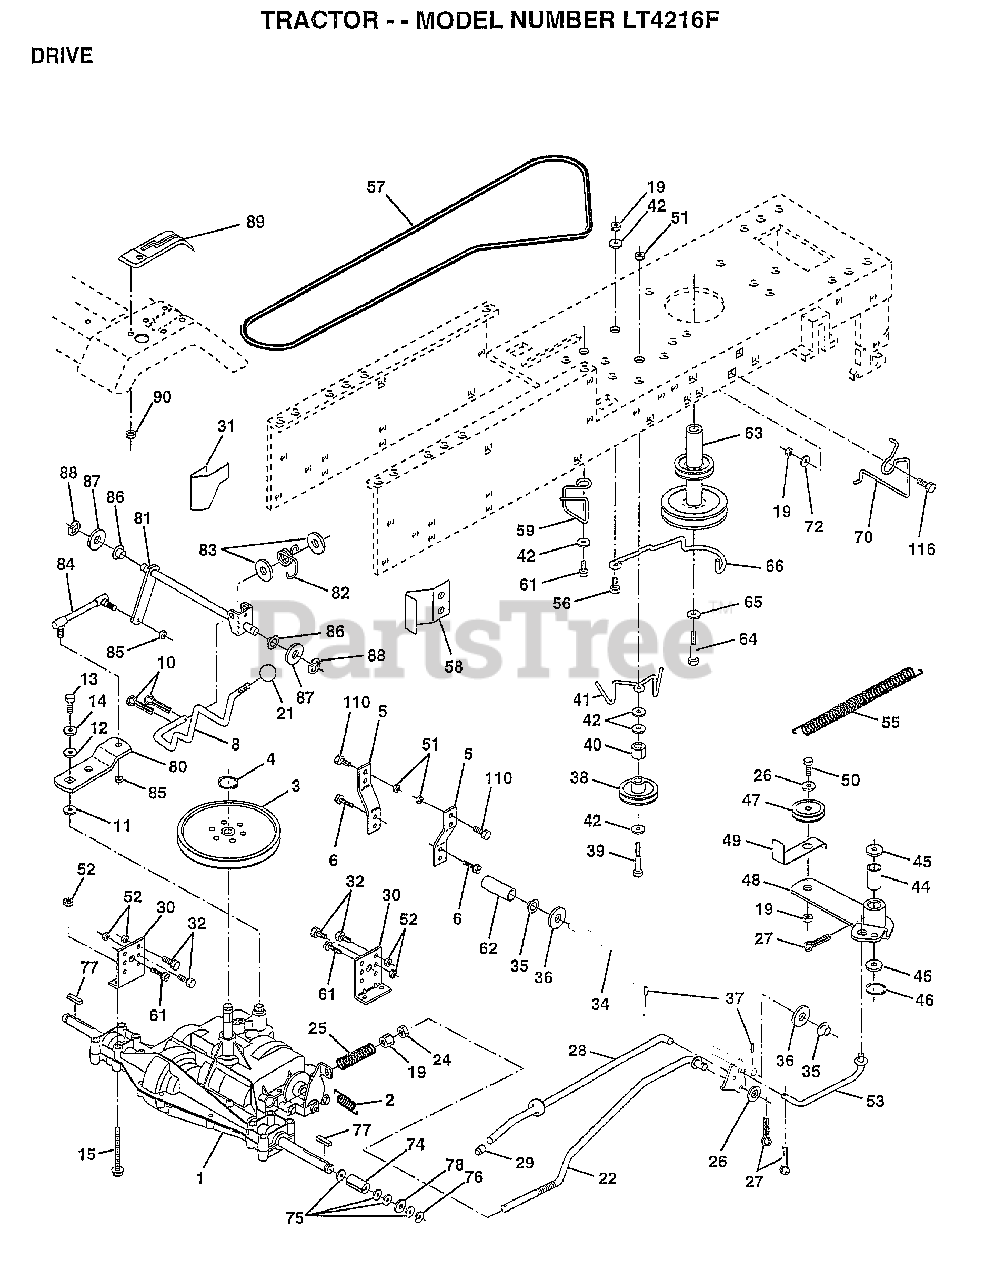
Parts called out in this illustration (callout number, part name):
2	SPRING.BRAKE.RETU
3	PULLEY TRANS
5	STRAP TORQUE
6	SCREW
8	ROD SHIFT FEND LT
10	PIN COTTER 1/8
11	WASH-SHFT PLT LT
12	WASHER
13	BOLT.1/4-28.W/PAT
14	LOCKWASHER
15	BOLT.HX.FLG.5/16
18	BOLT
19	NUT
21	KNOB T (1/2-HOLE)
22	BRAKE ROD
24	NUT
25	SPRING ROD LT
26	WASHER
27	COTTER PIN
28	ROD.BRAKE.PARK.LT
29	PLUNGER CAP T
30	TRANSAXLE MTG BKT
31	"KEEPER,BELT LH T"
32	BOLT
34	SHAFT FOOT PEDAL
35	NYLON BEARING
36	WASHER LT
38	PULLEY.IDLER.FLAT
39	BOLT
40	SPACER T
41	KEEPER BELT
42	WASHER
44	"LY, BEARING"
45	WASHER LT
46	KLIP RING
48	ARM IDLER
49	RETAIN BELT
53	"LINK, CLUTCH T"
55	"SPRING, RETURN LT"
58	"KEEPER,BELT RH T"
59	KEEPER BELT CNTSP
61	SCREW
62	PEDAL COVER T
63	PULLEY.ENGINE
64	BOLT HEX 7/16-20X4 GR 5
65	LOCKWASHER
70	KEEPER BELT ENG
72	WASHER
74	SPACER LT
75	WASHER
76	E-RING LT
77	SQUARE KEY
78	WASHER
80	ARM SHIFT TRANS
81	SHAFT ASM.SHIFT
82	"SPRING,TORSION"
83	WASHER
84	TIE ROD
85	NUT.CNT.LOCK.1/4
86	BUSHING
87	WASHER D
88	KLIP RING
90	NUT
116	BOLT RDHD 3/8-16
